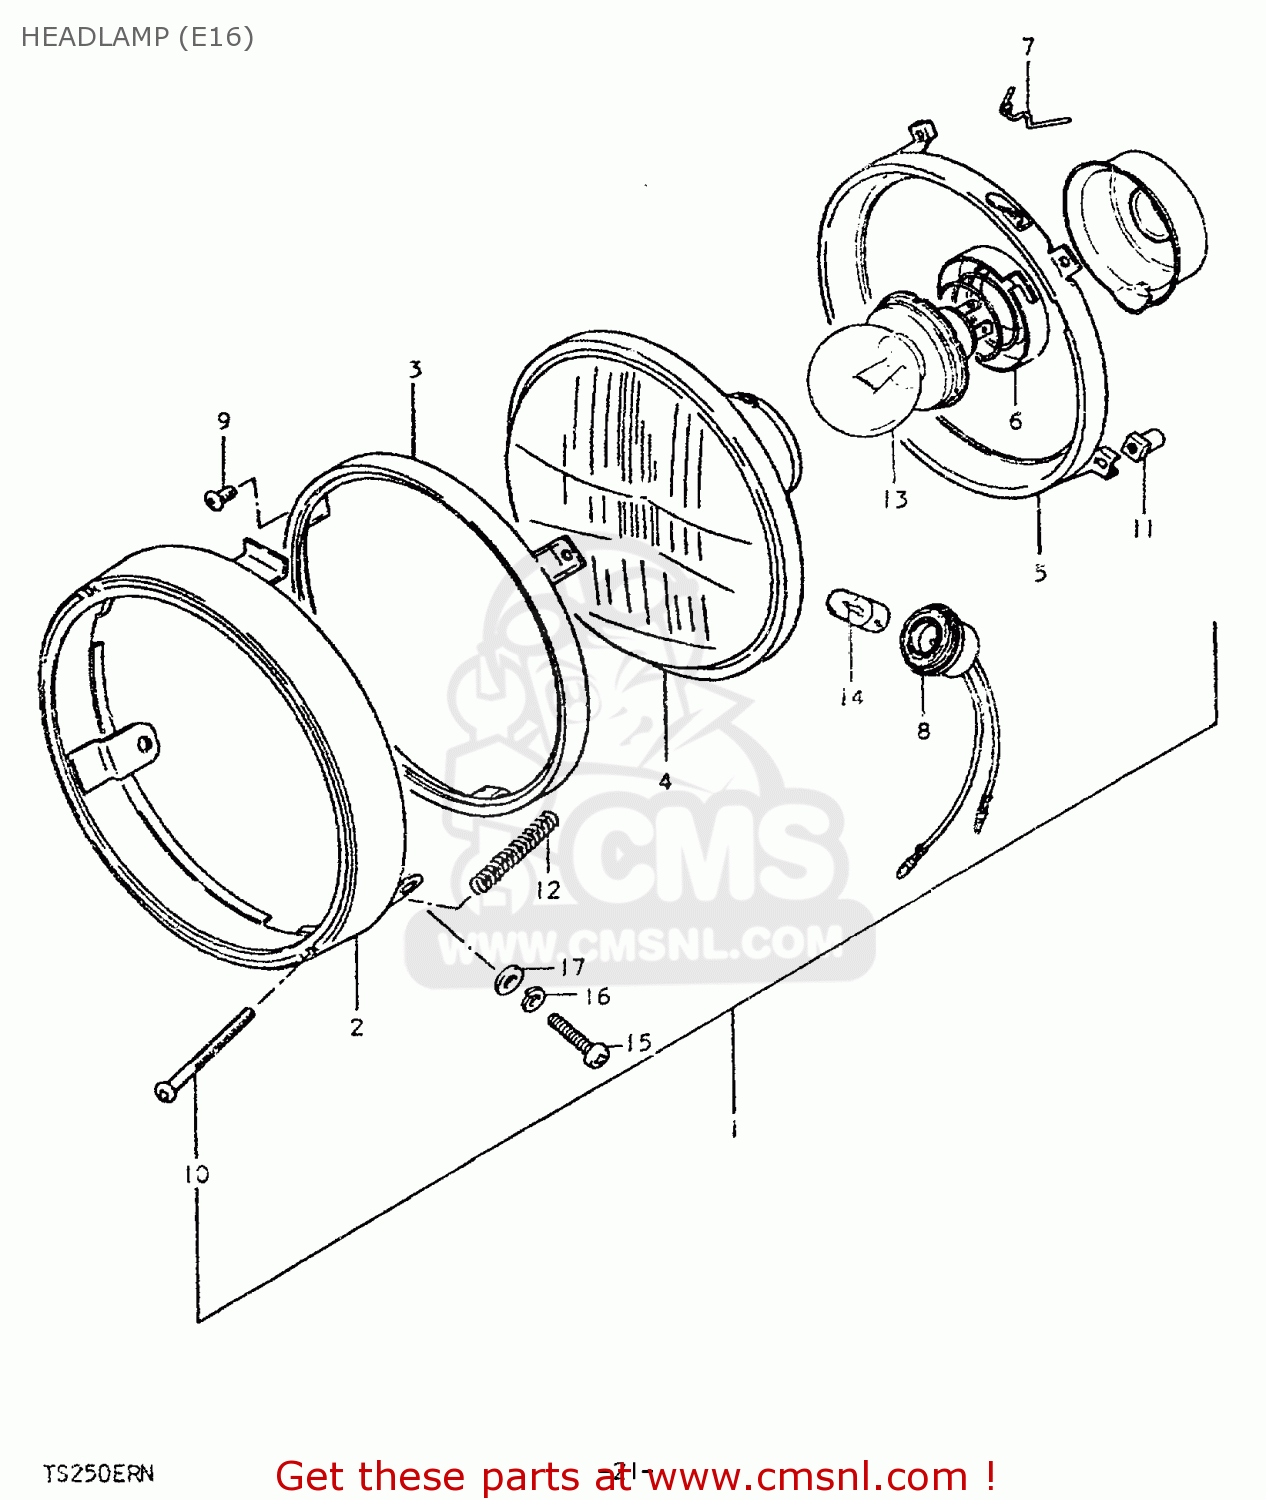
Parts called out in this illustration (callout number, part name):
1	HEADLAMP ASSY
2	RIM
3	RETAINER,HEADLAMP
4	UNIT
5	RING,HEADLAMP UNIT
6	SETTER,BULB
7	SPRING,HEADLAMP UNIT
8	SOCKET
9	SCREW
10	SCREW,HEADLAMP ADJUST
11	NUT,HEADLAMP ADJUSTER
12	SPRING,ADJUSTING
13	BULB (6V,45/40W)
14	BULB(6V4W,STANLEY,A1364J)
15	SCREW
16	LOCK WASHER
17	WASHER
